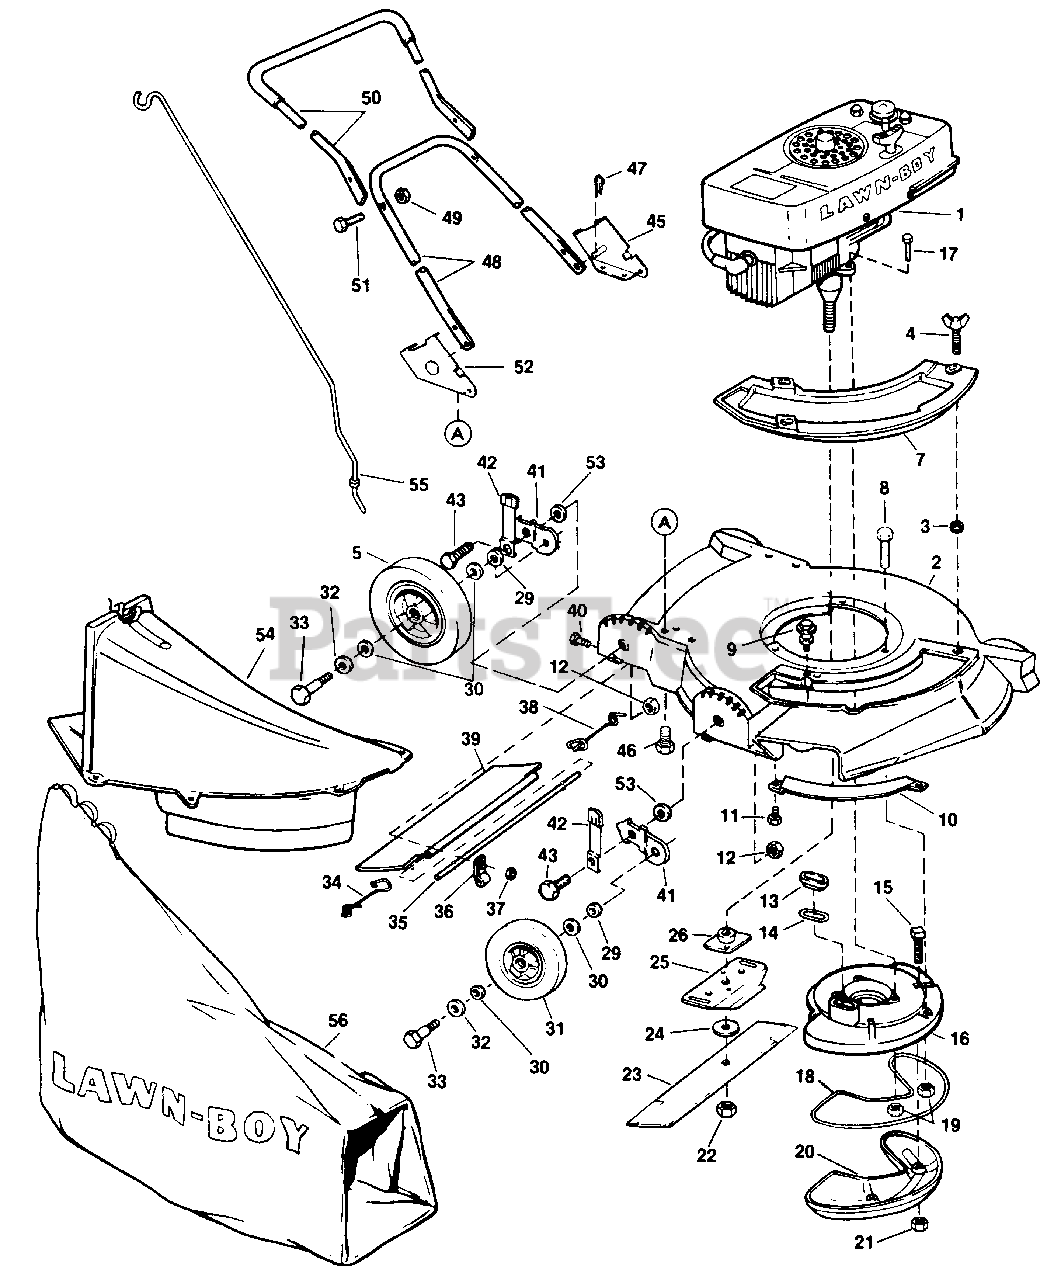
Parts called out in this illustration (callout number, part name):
2	Housing & Cover Plate-21"
3	Grommet (Also Included in 681536 19" Housing)
4	Screw (Also for 19" Models)
5	Wheel & Tire-8"
7	Cover-Chute (19" & 21" Model)
8	Screw-Muffler Plate to Housing
9	Bolt
10	Toe Bar-19" Models
10	Toe Bar-21" Models
11	Screw
12	Nut
13	Sleeve-Muffler Gasket
14	Gasket-Exhaust
15	Screw-Muffler Muffler Plate
16	Muffler Plate Assy
17	Screw
18	Gasket-Muffler
19	Nut
20	Muffler
21	Nut-Muffler
22	Nut-Blade
23	Blade-21"
23	Blade-19"
24	Washer (21" Models Only)
25	Stiffener-Blade
26	Collar & Plate Assembly
29	Washer
30	Felt Washer
31	Wheel & Tire-6"
32	Washer-Wheel Bolt Head
33	Bolt-Shoulder, Wheel-Front & Rear
34	Spring-R.H.
35	Rod-19" Models
35	Rod-21" Models
36	Clamp
37	Nut
38	Spring-L.H.
39	Shield-19" Models
39	Shield-21" Models
40	Screw
41	Wheel Hgt. Adj. Bracket
42	Knob & Spray Ay.
43	Bolt-Shoulder
45	Bracket-Handle-Left
46	Screw
47	Hairpin
48	Handle-Bottom
49	Nut-Handle
50	Handle-Top
51	Screw-Handle
52	Bracket-Handle-Right
53	Washer
54	Chute
55	Rod
56	Grass Bag
